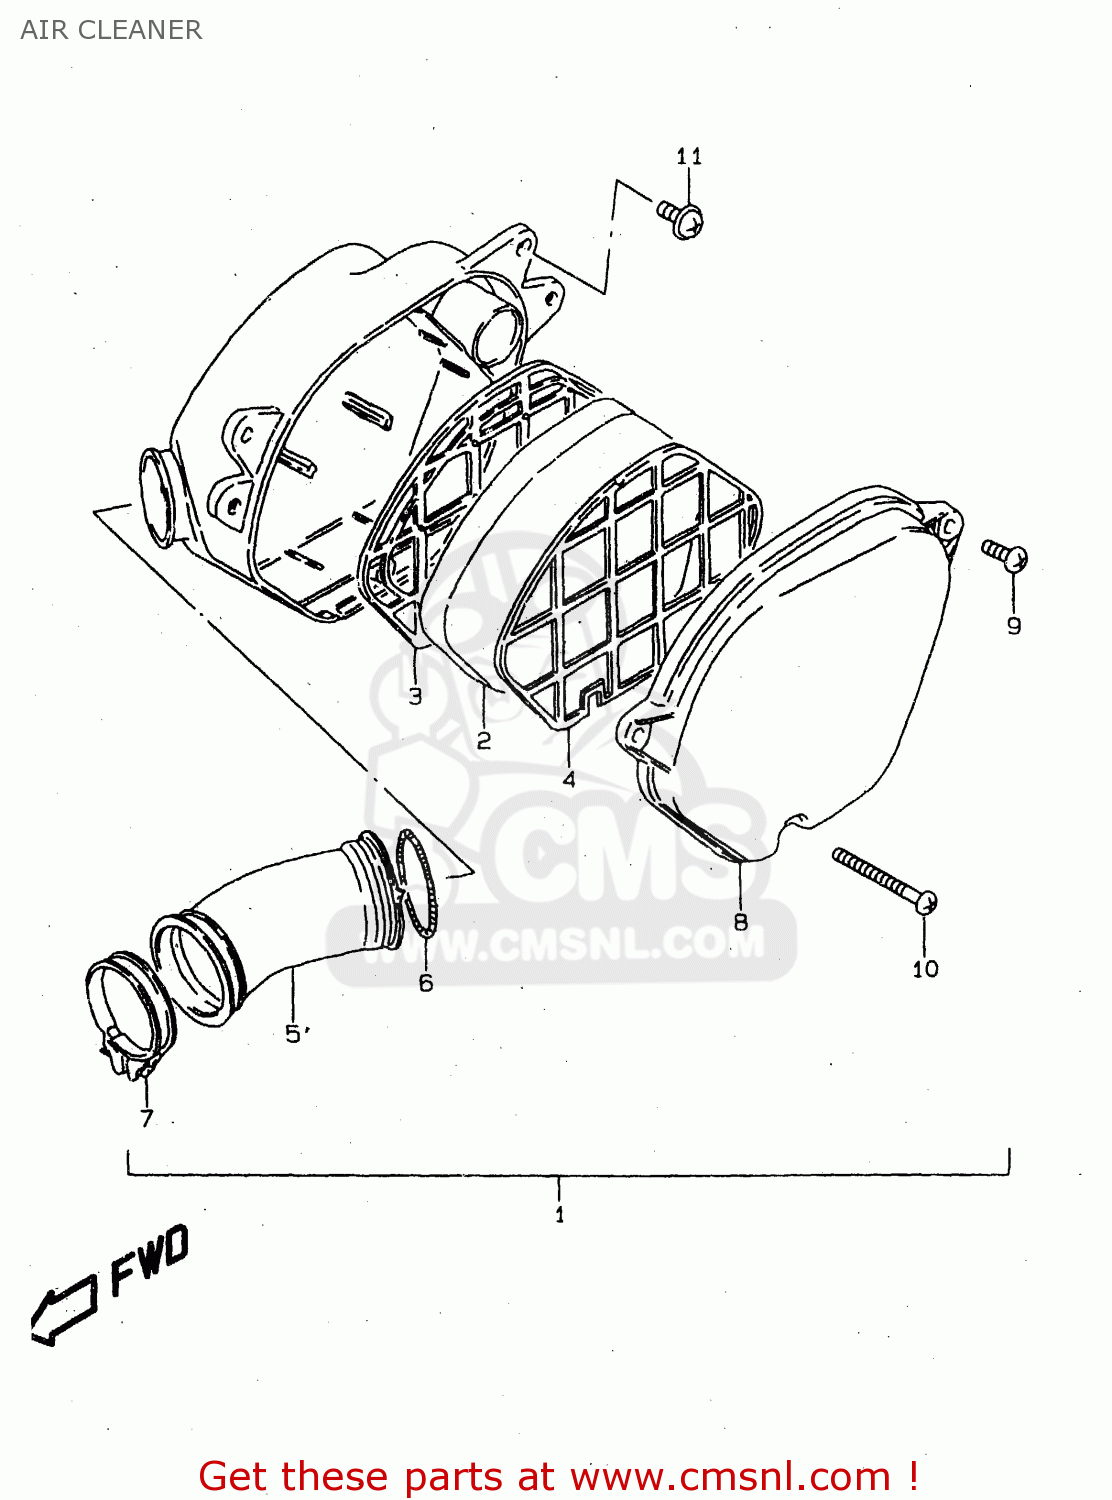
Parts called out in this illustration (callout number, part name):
1	CLEANER ASSY,AIR
2	FILTER
3	HOLDER,FILTER INNER
4	HOLDER,FILTER OUTER
5	TUBE,OUTLET
6	SPRING,AIR CLEANER SIDE
7	CLAMP
8	CAP,CLEANER
9	SCREW
10	SCREW
11	SCREW(6X16)
